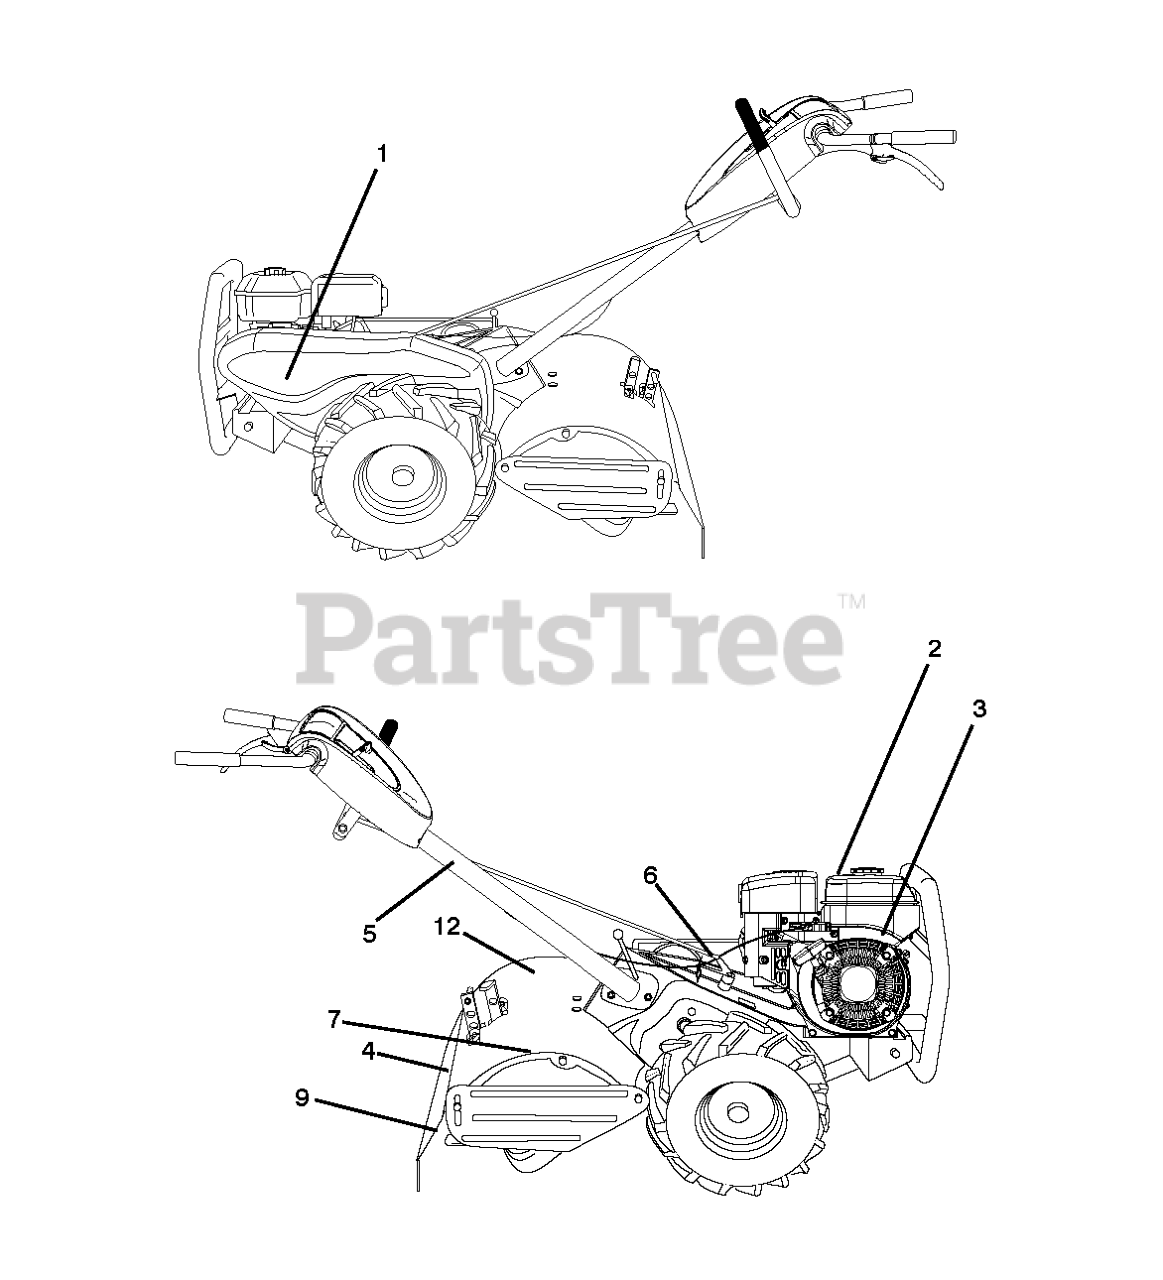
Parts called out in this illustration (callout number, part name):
1	RP.DECAL.BADGE.170MM.TEXTLOGO
2	DECAL,ETHANOL E85 WARNING
3	DECAL, WARNING SPARK ARRESTOR
4	DECAL.SHIELD.TN.DRT17.HUSQ
5	DECAL TI (2 2)
6	DECAL.SHIFT.INDICATOR.DRT
7	DECAL.REVERSE.HUSQ.TILLER
9	DECAL.DRT.WARN.ENG/F
12	DECAL.FOWARD.HUSQ.TILLER
